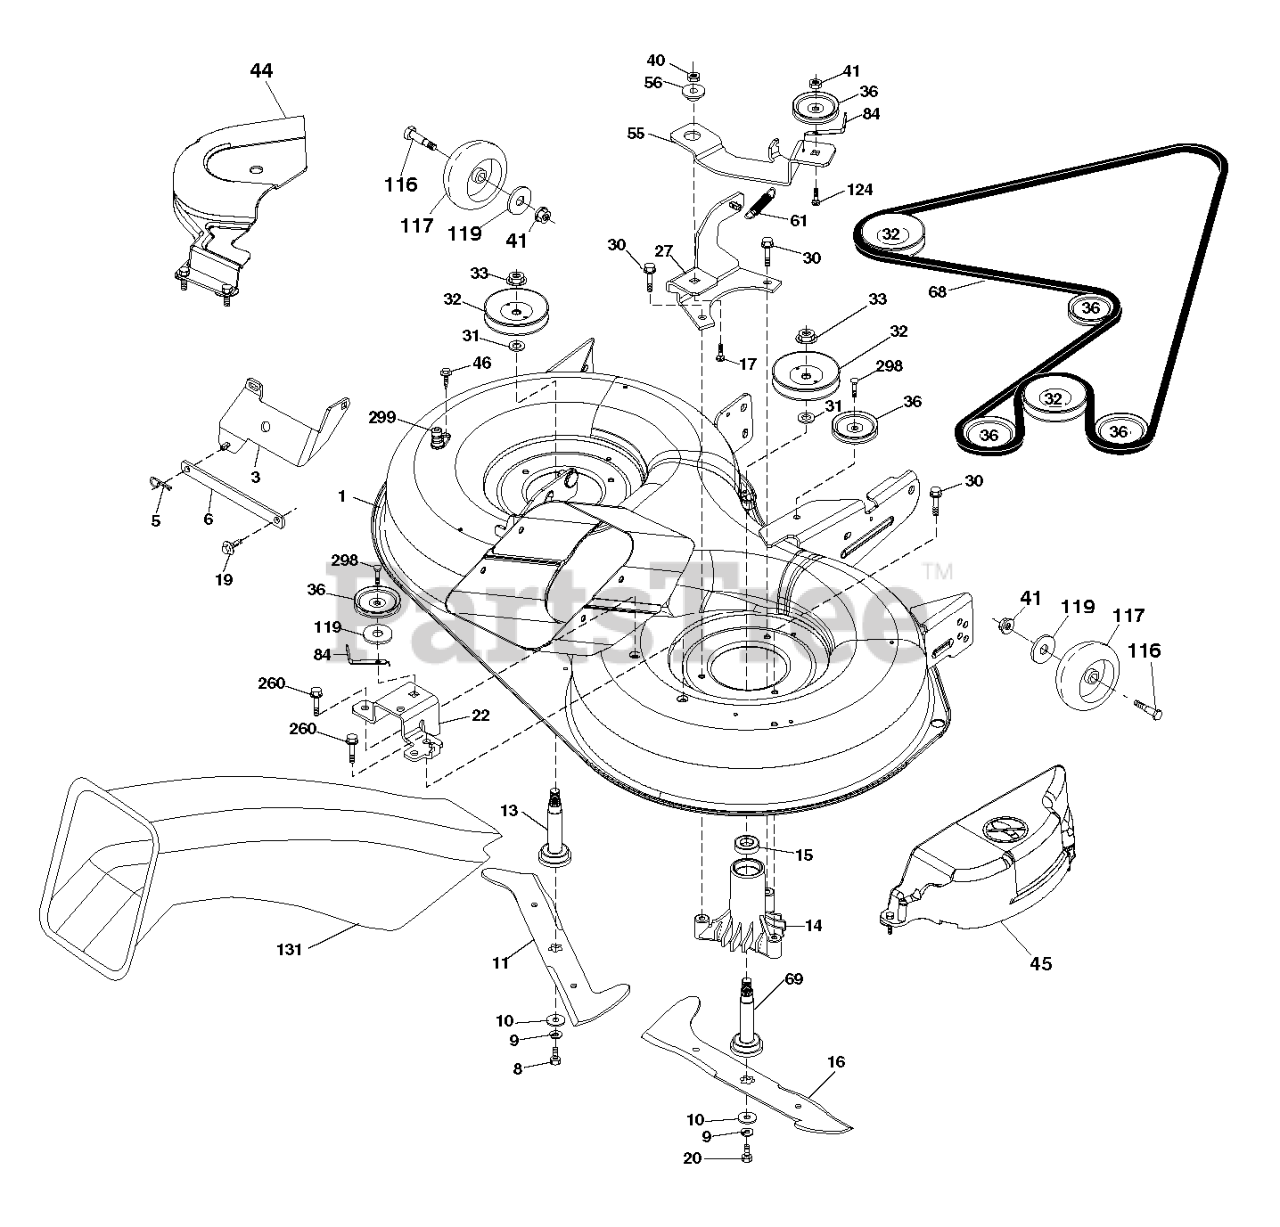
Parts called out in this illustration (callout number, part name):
3	BRACKET.ASM.BAR.SWAY.CHASS
5	RETAINER-SPRNG RB
6	BAR.SWAY.92.CRD
8	BOLT.3/8-24X1.25 GR8
9	LOCKWASHER
10	WASHER.BLADE
11	BLADE.3N1.LH.CRD.97
13	SHAFT ASM VENT
14	HOUSING.MANDREL.VENTED (MACHD)
16	BLADE.3N1.RH.CRD.97
17	BOLT.3/8-14X1.25
19	BOLT SHD 5/16-18
20	BOLT.3/8-24X1.25GR8. LHTHRD
22	BRACKET.SUPT.IDLER.REAR.RH
27	BRACKET.ASM.SUSP.REAR.RH.
30	SCREW, WASHER HEAD
31	WASHER.SPACER.MANDREL
32	PULLEY MANDREL
33	NUT.FLANGE.LOCK.TOP
36	PULLEY.IDLER.4.25
41	NUT LOCK FLG 3/8-16 UNC
46	SCREW.1/4-20X5/8
55	ARM.IDLER.92 CRD.2006
56	SPACER.RETAINER.MOWER
61	SPRING
68	BELT.DRIVE.CRD.97.2010
69	SHAFT.ASM.W/LWR.BRG.RH.THREAD
84	KEEPER, BELT IDLER
116	BOLT.SHOULDER.3/8-16X3-5/8.
117	RP WHEEL. GUAGE RALLY
119	WASHER
124	BOLT.3/8-16X1.50
131	CHUTE BAGGER
260	SCREW 3/8-16X1/2
298	SCREW LT
299	PORT.WASHOUT
